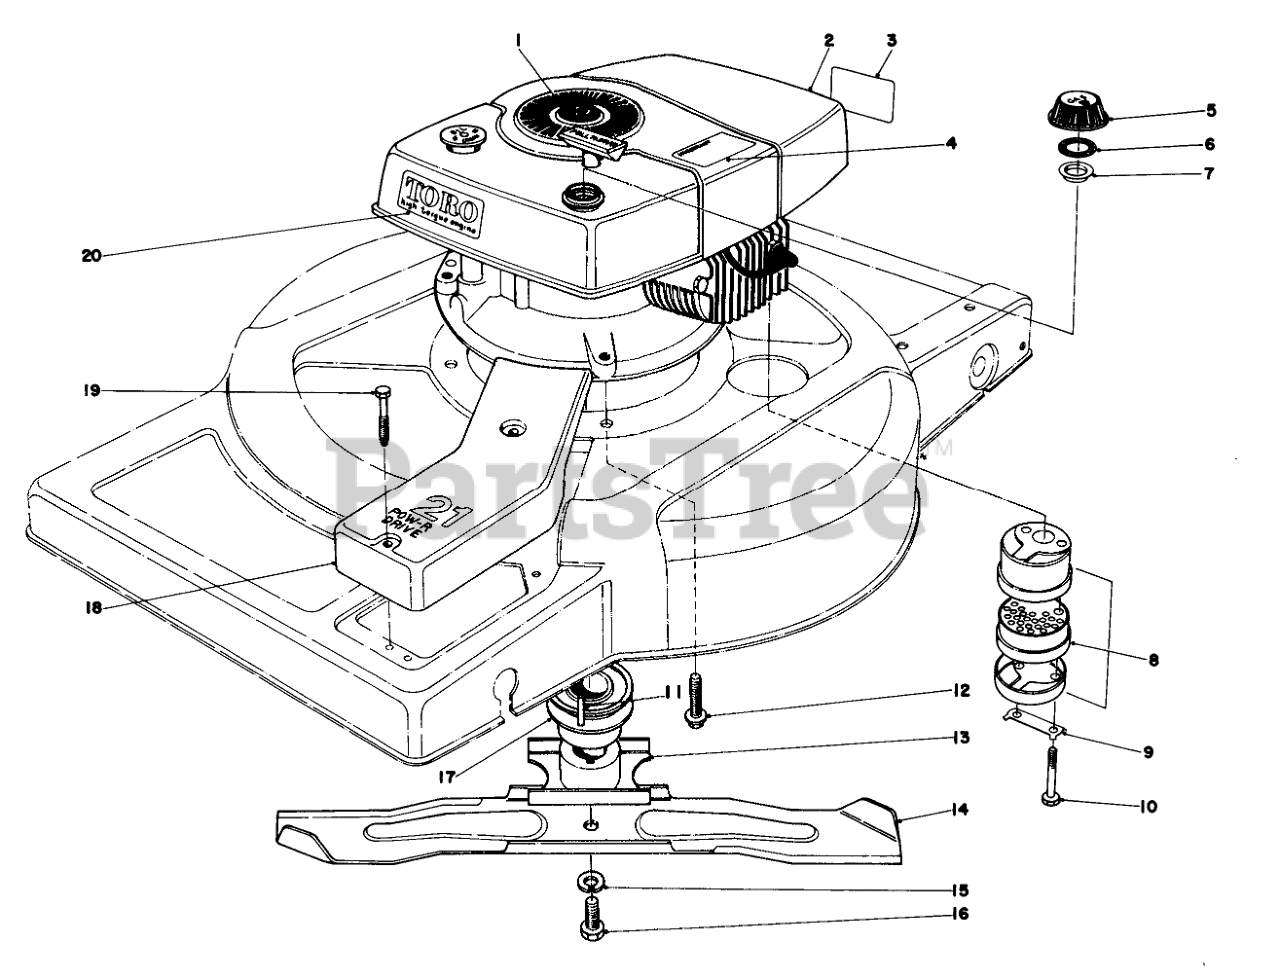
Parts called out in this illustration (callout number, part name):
1	Plug Button
2	Engine
3	Decal-Maintenan
4	Decal Lockout
5	Gas Cap Assembly (Incl. Ref. #6 & 7)
6	GASKET
7	GAS CAP BAFFLE
8	Muffler Assembly
9	CLIP - LOCKING
10	SCREW-HH
11	KEY-SQUARE
12	SCREW-HWHTF
13	BLADE RETAINER WA(BLACK)
14	Blade
15	WASHER-LOCK
16	BLADE SCREW
17	Pulley
18	COVER BELT
19	SCREW-HHFTF
20	High Torque
